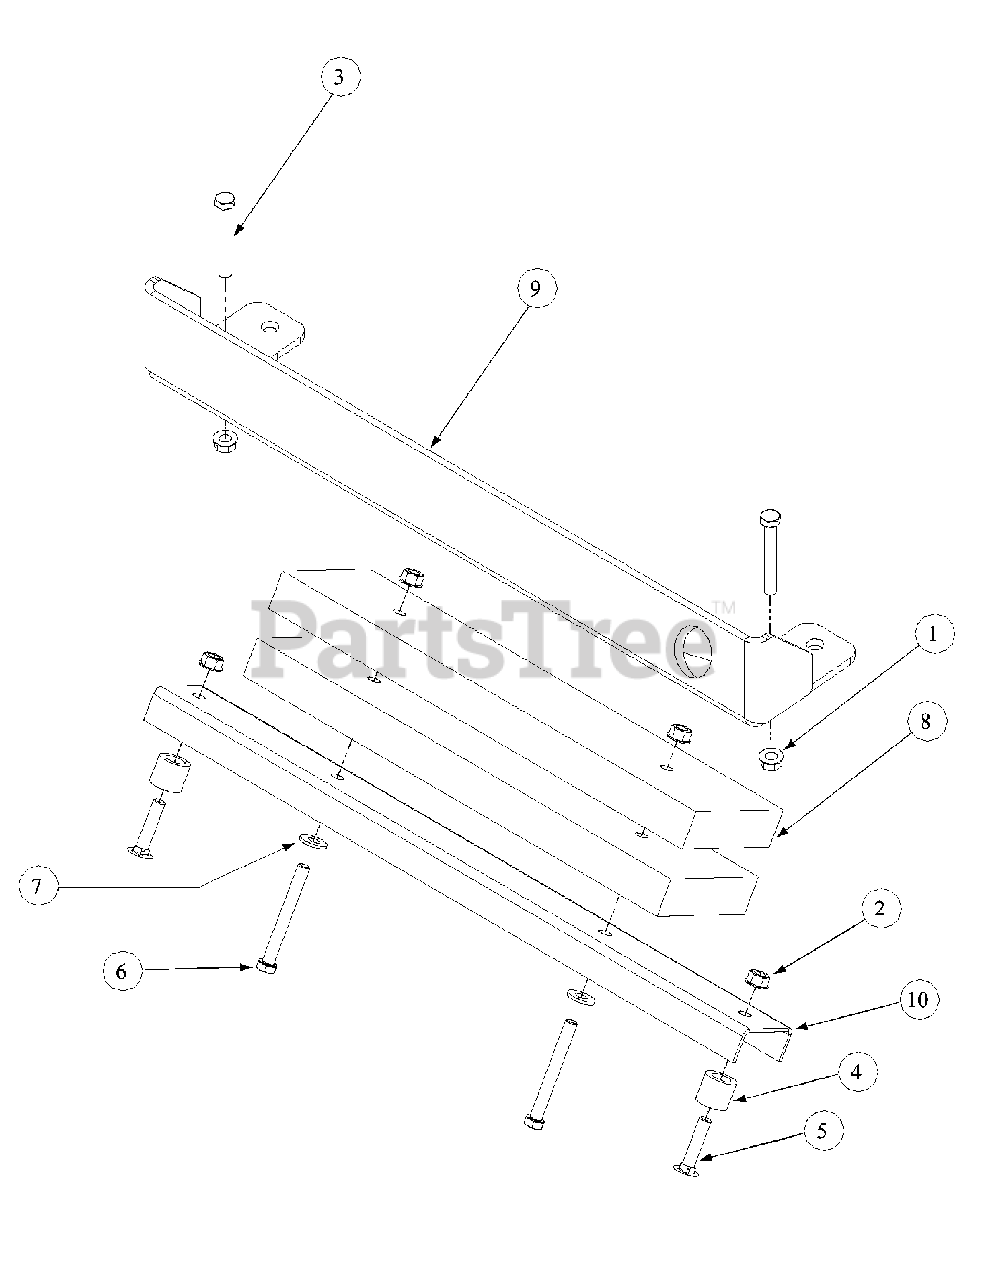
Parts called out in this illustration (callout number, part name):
1	Hex Nut, 1/2-13, Insert Lock
2	Nut, Hex 3/8-16 Flange Lock
3	HHCS, 1/2-13, 3.00
4	Spacer Crossbar
5	Carriage Bolt, 3/8-16, 1.75
6	HHCS, 3/8-16, 3.25
7	Flat Washer, .406 ID x 1.0 OD x .105
9	Rear Bumper Plate
10	Bumper Cross Bar-Rear
